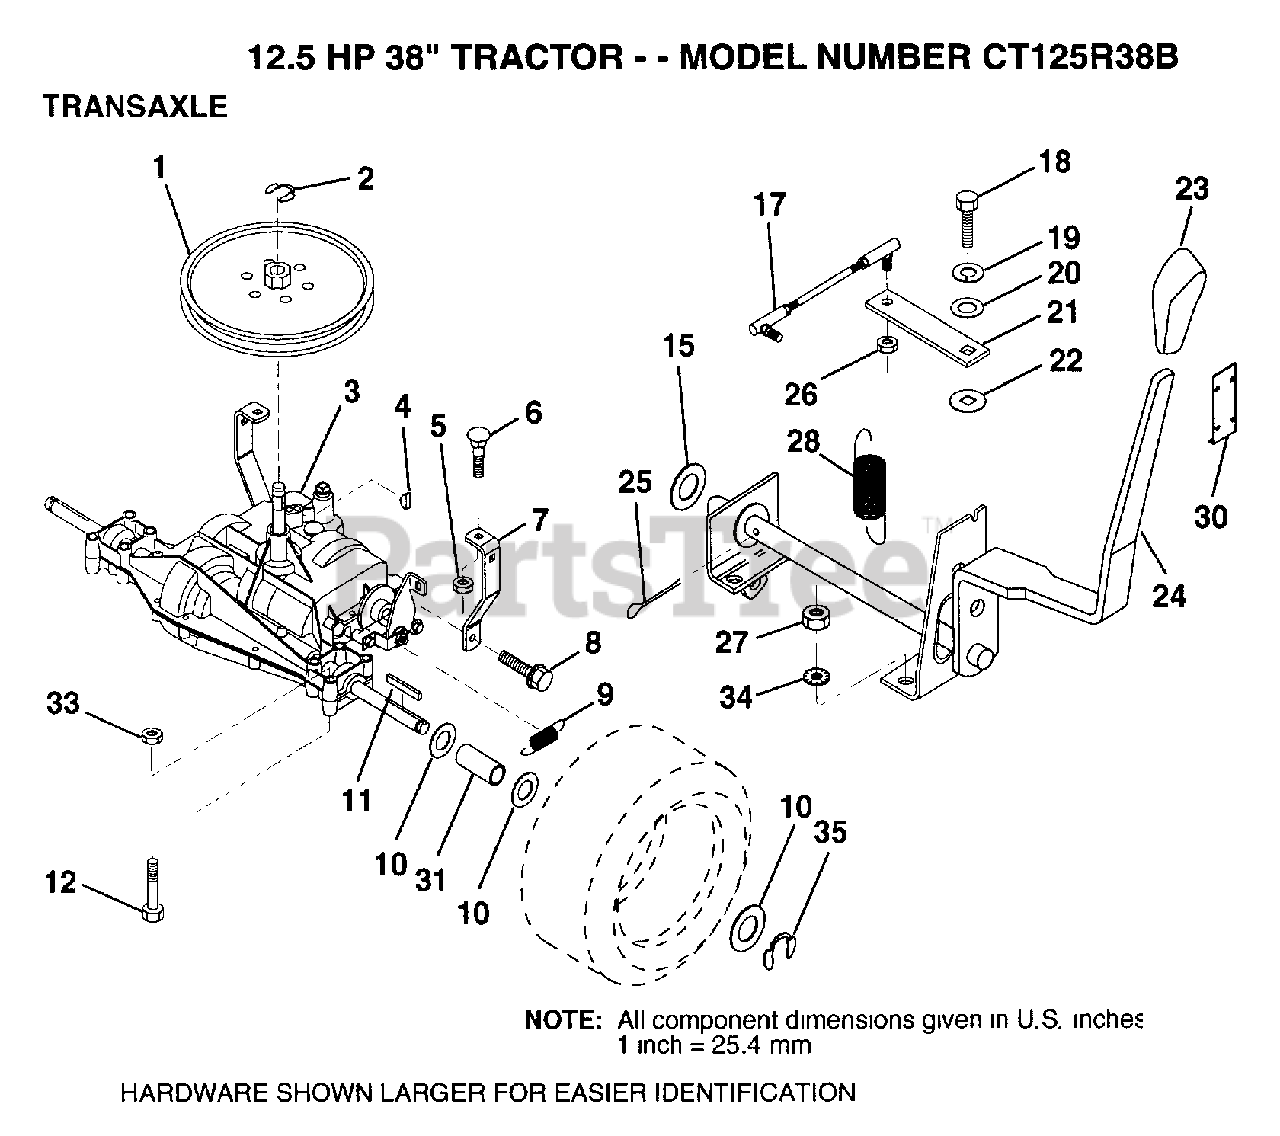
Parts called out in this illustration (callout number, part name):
1	PULLEY
3	TRANSAXLE.6SP.D
6	BOLT
7	"STRAP,TORQUE"
8	SCREW
10	WASHER
11	SQUARE KEY
12	BOLT
17	"LINK,SHIFT"
19	LOCKWASHER
20	WASHER LT
21	"ARM,SHIFT"
22	GRIP CRT
23	"KNOB,SHT CONTROL"
25	PIN COTTER 1/8
26	NUT.LOCK.5/16-24
28	"SPRING,EXT"
30	KNOB RETAINER
31	SPACER
34	LOCKWASHER.5/16.E
35	E-RING LT
